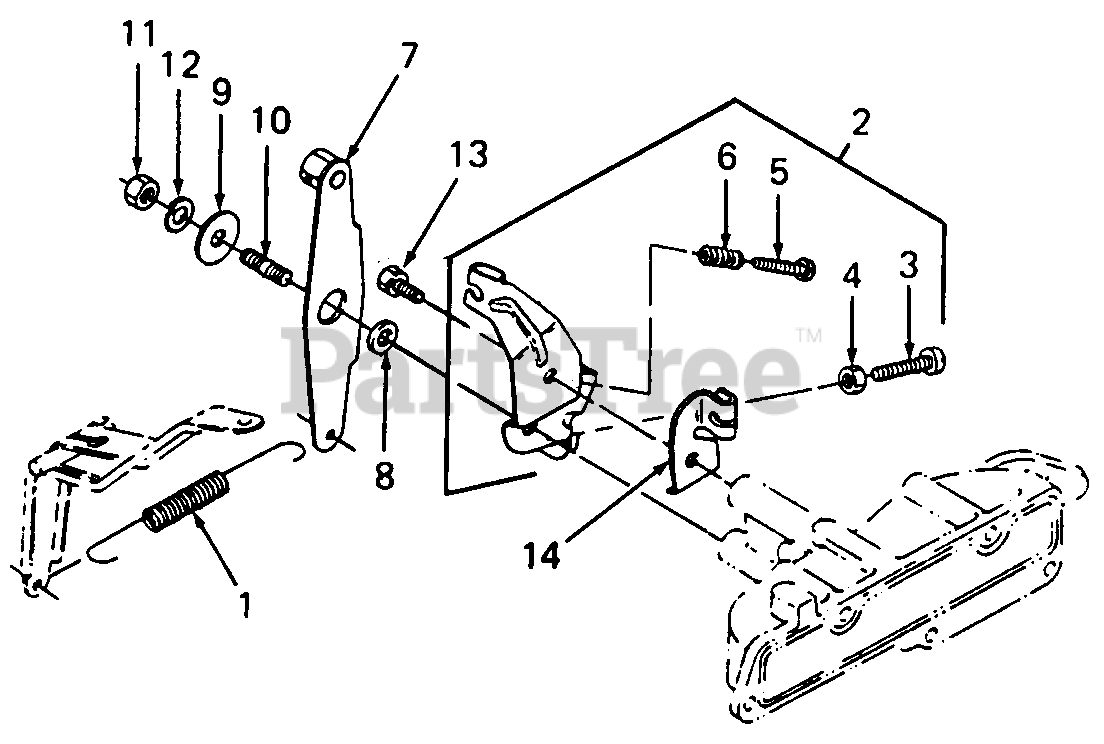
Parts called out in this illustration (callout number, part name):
1	Spring, Governor
2	Control Plate Assy
3	Screw, Pan Head
7	Control Lever Assy
9	Washer, Plain
12	Washer, Spring
14	Stay, Choke Wire
